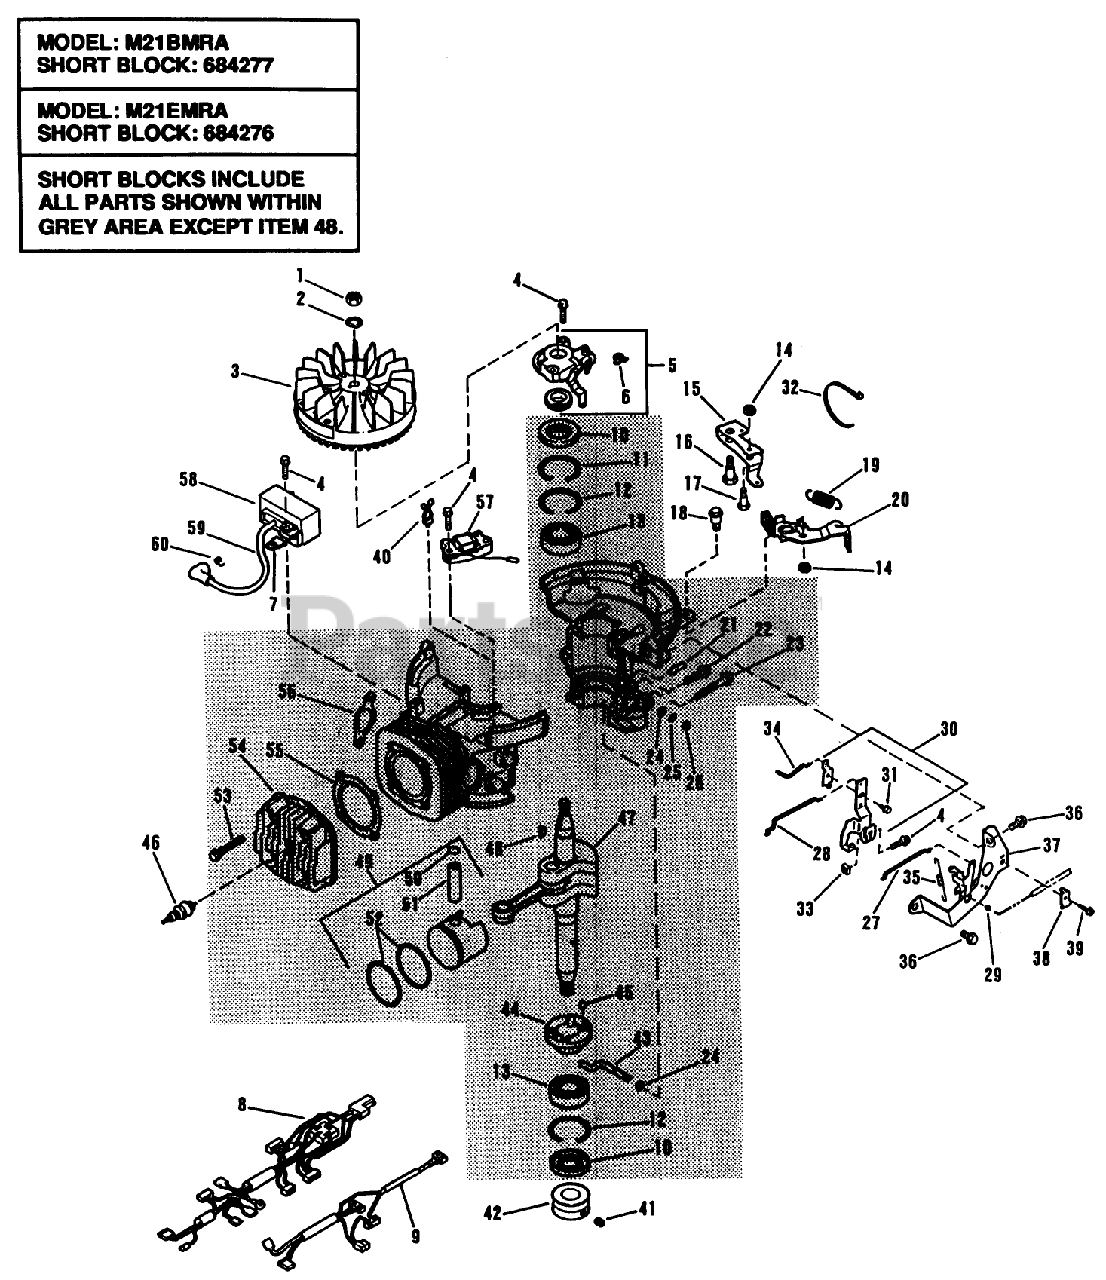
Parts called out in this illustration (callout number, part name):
1	NUT
3	FLYWHEEL AY SM
4	SCREW
8	WIRE HARNESS
10	SEAL - OIL SM
11	RING-RETAINER SM
13	BEARING-BALL SM
14	LOCKNUT E
15	ACT.BRAKE LVR. SM
16	SCREW-SHOULDER
19	SPRING-BRAKE
22	SCREW-H.W.HD. F
23	SCREW-HEX W.H. SM
25	RING-RETAINING
26	SEAL - OIL SM
28	ROD-THROTTLE SM
31	SCREW
35	SPRING-GOV. SM
37	GOVNR BRKT SM
40	WIRE TIE SM
42	PULLEY-ENGINE
46	SPARK PLUG
47	Crankshaft and Connecting Rod
48	KEY
52	RING SET S
53	SCREW
54	CYLINDER HEAD SM
56	GASKET - EXH SM
57	ALTERNATOR ASM
59	HI-TENS.LEAD
